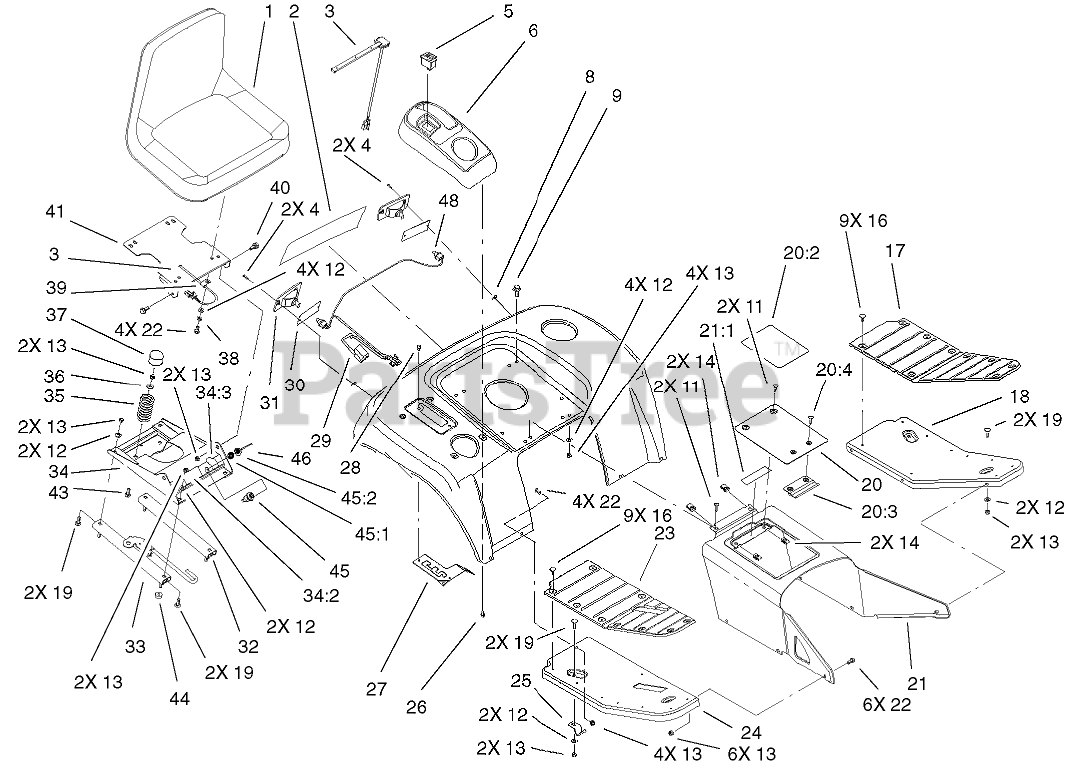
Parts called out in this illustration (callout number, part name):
1	Seat V-511 (only on: 73471)
1	Seat (only on: 73542, 73570)
2	DECAL - FENDER
3	SWITCH-SEAT
4	SCREW-PPH
5	Switch-Cruise (only on: 73542, 73570)
6	Pod-Control 18 HP (only on: 73471)
6	Pod-Control Int-l (only on: 73570)
6	Pod-Control (only on: 73542)
8	NUT-SPEED
9	SCREW-HHF
11	SCREW-HH
12	WASHER-PLAIN
13	NUT-LOCK, NI
16	FASTENER-PANEL
17	PAD-FOOTREST, LH
18	FOOTREST-LH
19	SCREW-CARR
20	Cover/Decal ASM (only on: 73471, 73542)
20	Tunnel Cover ASM (only on: 73570)
20:2	Decal-Danger (only on: 73570)
20:2	Decal-Danger (only on: 73471, 73542)
20:3	RETAINER-COVER
20:4	SCREW-PPH
21	Tunnel ASM (only on: 73471, 73542)
21	Tunnel ASM (only on: 73570)
21:1	Decal-Danger (only on: 73471, 73542)
21:1	Decal-Warning (only on: 73570)
22	SCREW-HH
23	PAD-FOOTREST, RH
24	FOOTREST-RH
25	BRACKET-FOOTREST
26	SCREW-HHFTF
27	GATE-HI / LO SHIFT
28	SCREW-HWH
29	Harness-Rear (only on: 73542, 73570)
30	Gasket-Tail Light (only on: 73471)
31	Lamp-Taillight (only on: 73542, 73570)
31	Reflector (only on: 73471)
32	SLIDE-SLAVE, SEAT
33	SLIDE-LATCH, SEAT
34	Seat Base ASM, Intl Decal (only on: 73570)
34	Seat Base ASM (only on: 73471, 73542)
34:2	Decal-Danger (only on: 73471, 73542)
34:2	Decal-Danger (only on: 73570)
34:3	Decal-Switch (only on: 73570)
34:3	Decal (only on: 73471, 73542)
35	SPRING-COMPRESSION
36	BUSHING
37	CAP-SPRING, SEAT
38	WASHER-LOCK
39	CLAMP-R
40	BOLT-SHOULDER
41	MOUNT-SEAT
43	SCREW-CARR
44	WASHER-FLAT
45	STARTER SWITCH ASM
45:1	WASHER-TOOTH, INTERNAL
45:2	NUT-HH
46	KEY-IGNITION
48	LIGHT BULB
